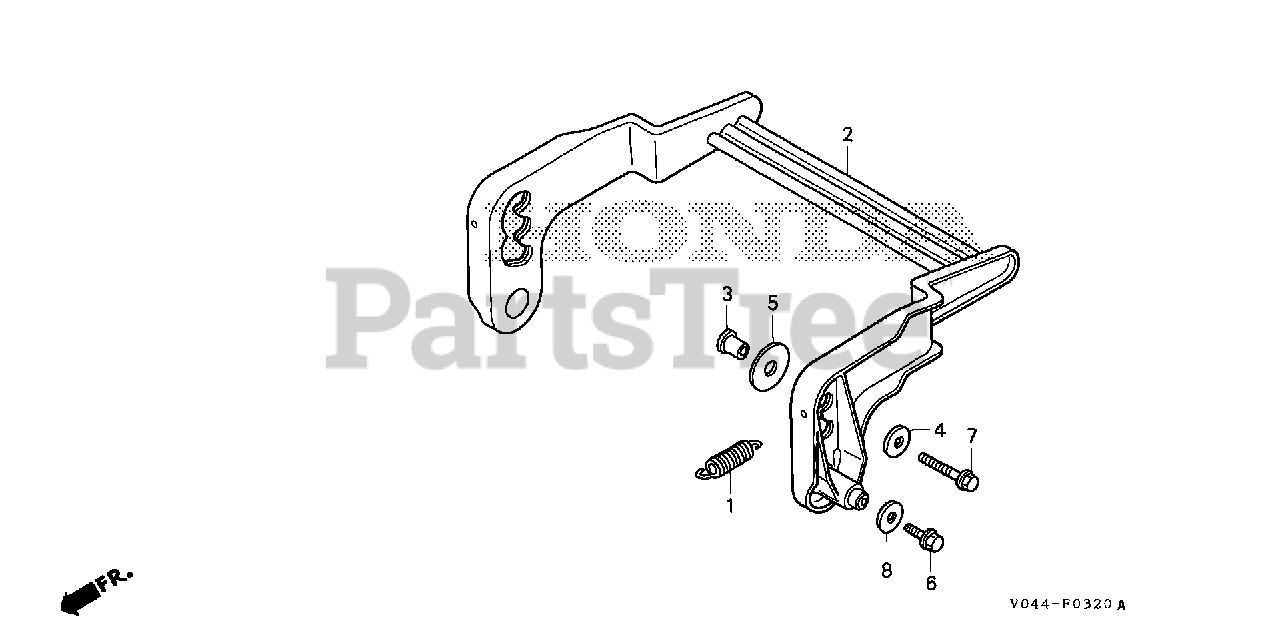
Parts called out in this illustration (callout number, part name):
1	SPRING, HEIGHT ADJUSTING
2	PLATE, HEIGHT ADJUSTING
3	COLLAR, HEIGHT ADJUSTING
4	WASHER, PLAIN (8X23X3.2)
5	WASHER, PLAIN (12MM)
6	BOLT, FLANGE (8X14)
7	BOLT, FLANGE (8X30)
8	WASHER, PLAIN (8MM)
